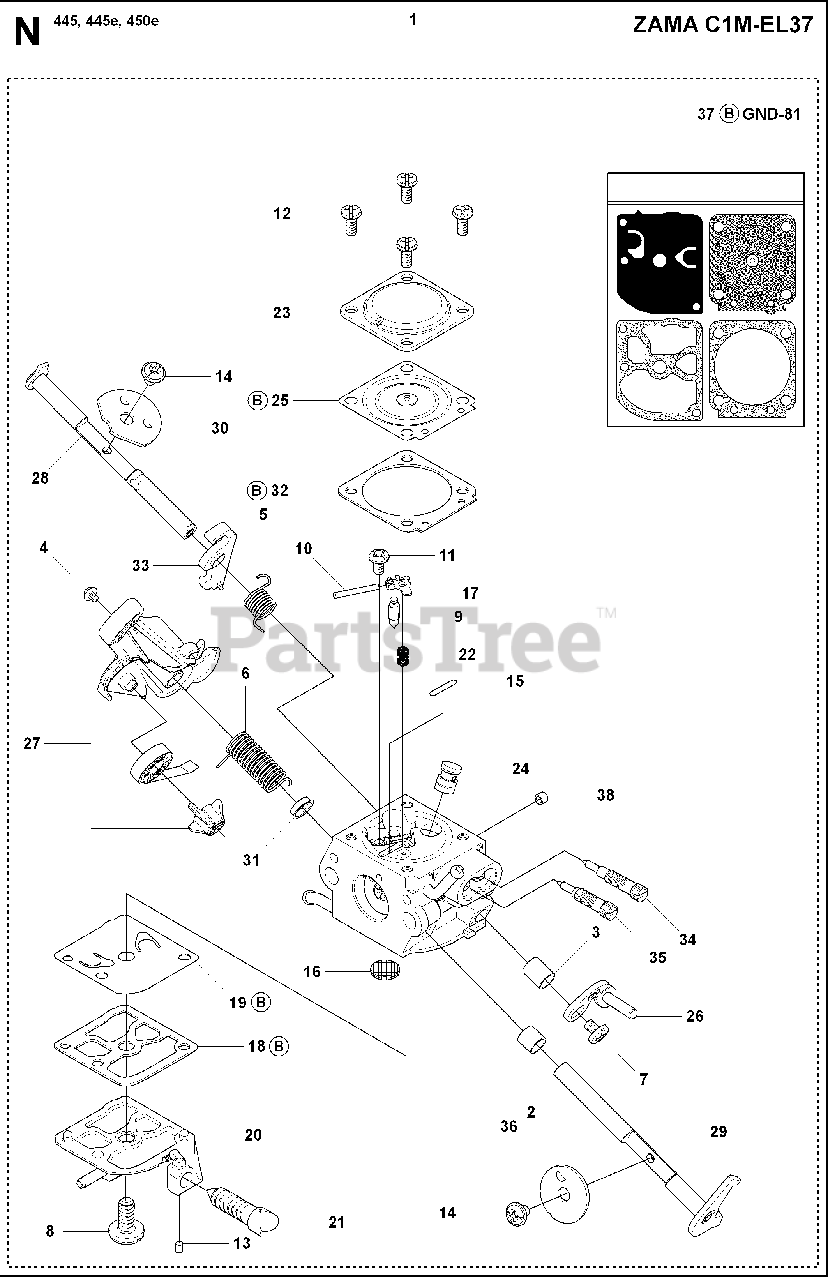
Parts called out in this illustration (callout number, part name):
1	%CARBURETOR
9	INLET NEEDLE
10	PIN FULCRUM
19	PUMP DIAPHRAGM
27	LEVER
28	Shaft Assembly
29	Shaft Assembly
37	GASKET KIT
